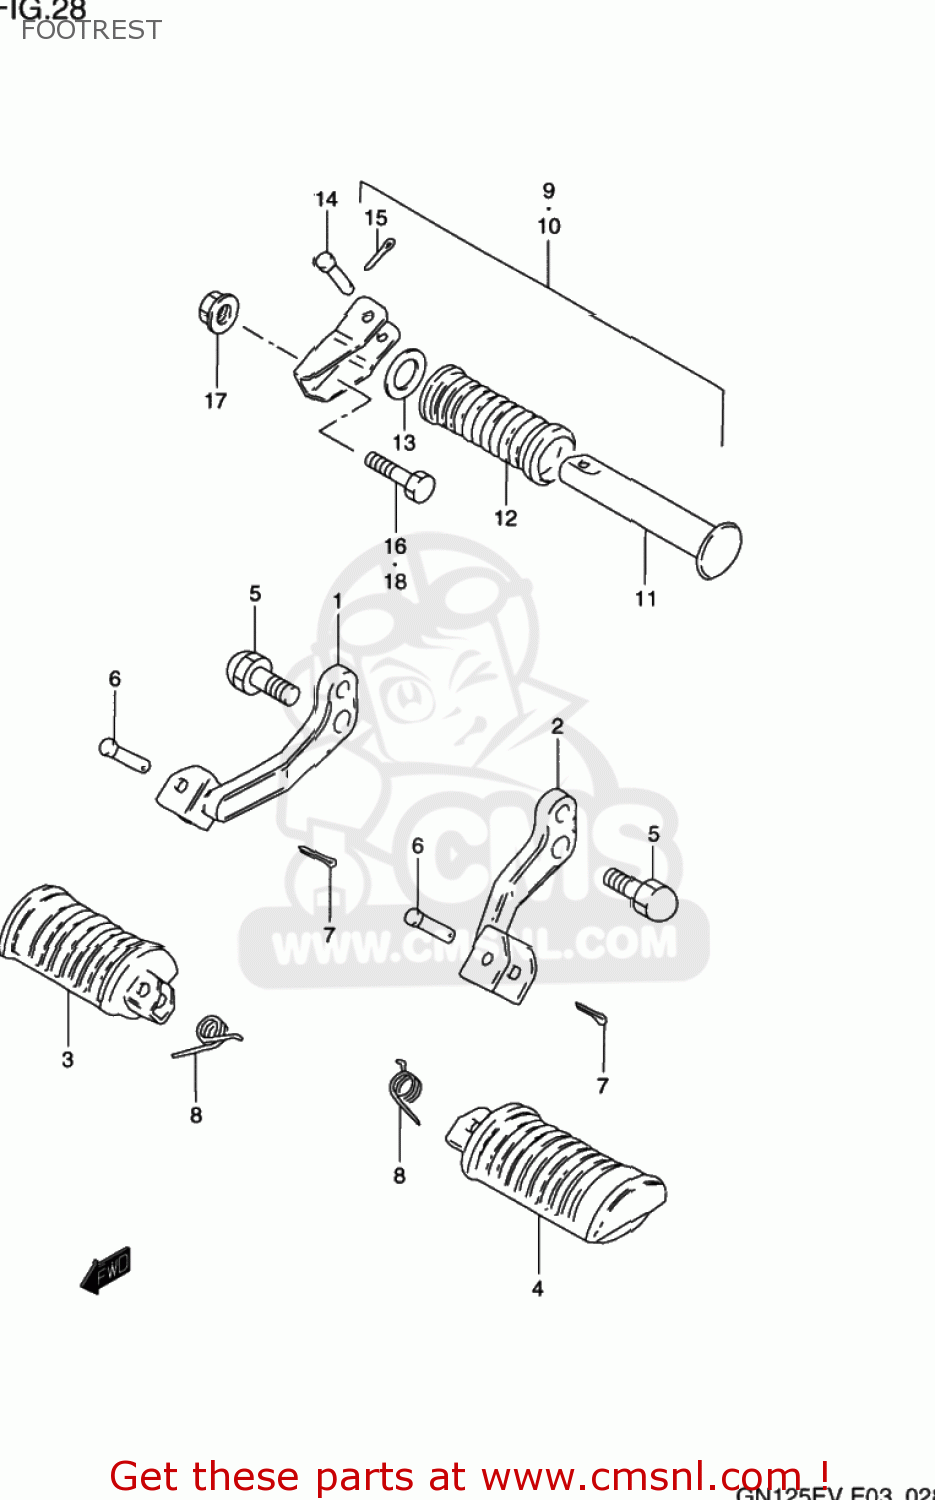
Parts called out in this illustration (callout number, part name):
1	HOLDER,FR FOOTREST,R
2	HOLDER,FR FOOTREST,L
3	RUBBER,PILLION FOOTREST,R
4	RUBBER,PILLION FOOTREST,L
5	BOLT
6	PIN
7	PIN 20X20
8	SPRING
9	FOOTREST ASSY,PILLION,R
10	FOOTREST ASSY,PILLION,L
11	BAR,FOOTREST RUBBER
12	RUBBER,PILLION FOOTREST
13	WASHER (19.5X32X2)
14	PIN
15	PIN
16	BOLT
17	NUT
18	BOLT
